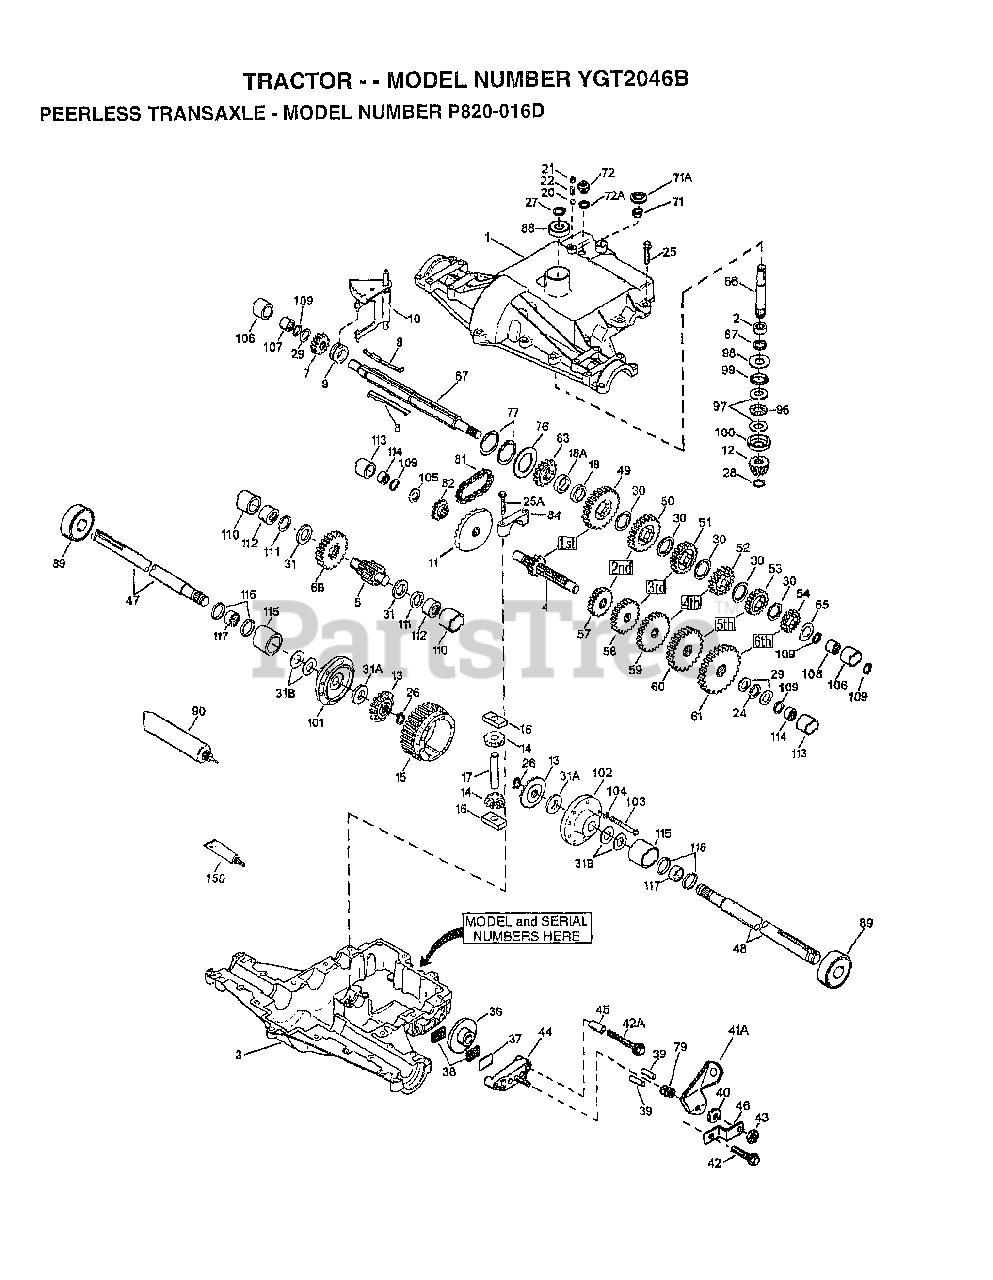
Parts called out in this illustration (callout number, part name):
1	COVER TRANSAXLE
2	BEARING NEEDLE
3	CASE TRANSAXLE
4	SHAFT COUNTER
5	SHAFT, OUTPUT, 9T
6B	GEAR, OUTPUT, 35T
7	GEAR, SPUR, 15T
9	COLLAR, SHIFTER
11	GEAR BEVEL, 33T
12	BEVEL PINION, 13T
14	PINION, 10T
15	GEAR, RING, 31T
16	BLOCK DRIVE
18	SPACER, .350/.340 THICK
18A	SPACER, .276/.268 THICK
20	BALL STEEL, 5/16" DIA.
21	SCREW, 3/8-16 X 3/8"
24	THRUST BEARING
25	SCREW, 5/16-18 X 1-1/4
28	RETAINING RING
29	WASHER THRUST
30	WASHER THRUST
31	WASHER THRUST
31B	WASHER THRUST
37	PLATE BRAKE PAD
41A	LEVER BRAKE
42A	SCREW, 1/4-20 X 2-1/4
43	LOCKNUT 5/16-24
44	HOLDER BRAKE PAD
46	BRKT BRAKE LEVER
47	AXLE, 12-5/16" LONG
48	AXLE, 16-3/16" LONG
49	GEAR, SPUR, 41T
50	GEAR, SPUR, 35T
51	GEAR, SPUR, 30T
52	GEAR, SPUR, 25T
53	GEAR, SPUR, 22T
54	GEAR, SPUR, 19T
57	GEAR, SPUR, 15T
58	GEAR, SPUR, 20T
59	GEAR, SPUR, 25T
60	GEAR, SPUR, 28T
61	GEAR, SPUR, 31T
65	WASHER, THRUST
66	SHAFT INPUT
67	SHIFTER & BRAKE SHAFT
71	SEAL SQUARE CUT
72	THREADED PLUG 9/16-18
76	WASHER, THRUST
77	INVERTED RETAINING RING
81	CHAIN, ROLLER
82	SPROCKET 9T
83	SPROCKET 18T (REV)
84	BEARING CAP
87	OIL SEAL 3/4
88	BEARING BALL
89	BEARING BALL
90	GREASE BENTONITE, 32 OZ.
96	BEARING THRUST
97	WASHER THRUST
100	WASHER CUPPED
101	CARRIER DIFF THREADED HOLES
102	CARRIER DIFF
103	SCREW, 1/4-20 X 2-1/4
104	WASHER LOCK 1/4
107	BEARING NEEDLE
108	BEARING NEEDLE
110	SLEEVE STEPPED
111	RING SQ CUT
112	BEARING NEEDLE CAPPED
113	SLEEVE STEPPED
114	BEARING NEEDLE CAPPED
115	SLEEVE STEPPED
116	RING SQ CUT
117	BEARING NEEDLE
150	LIQUID GASKET RTV SILICONE
